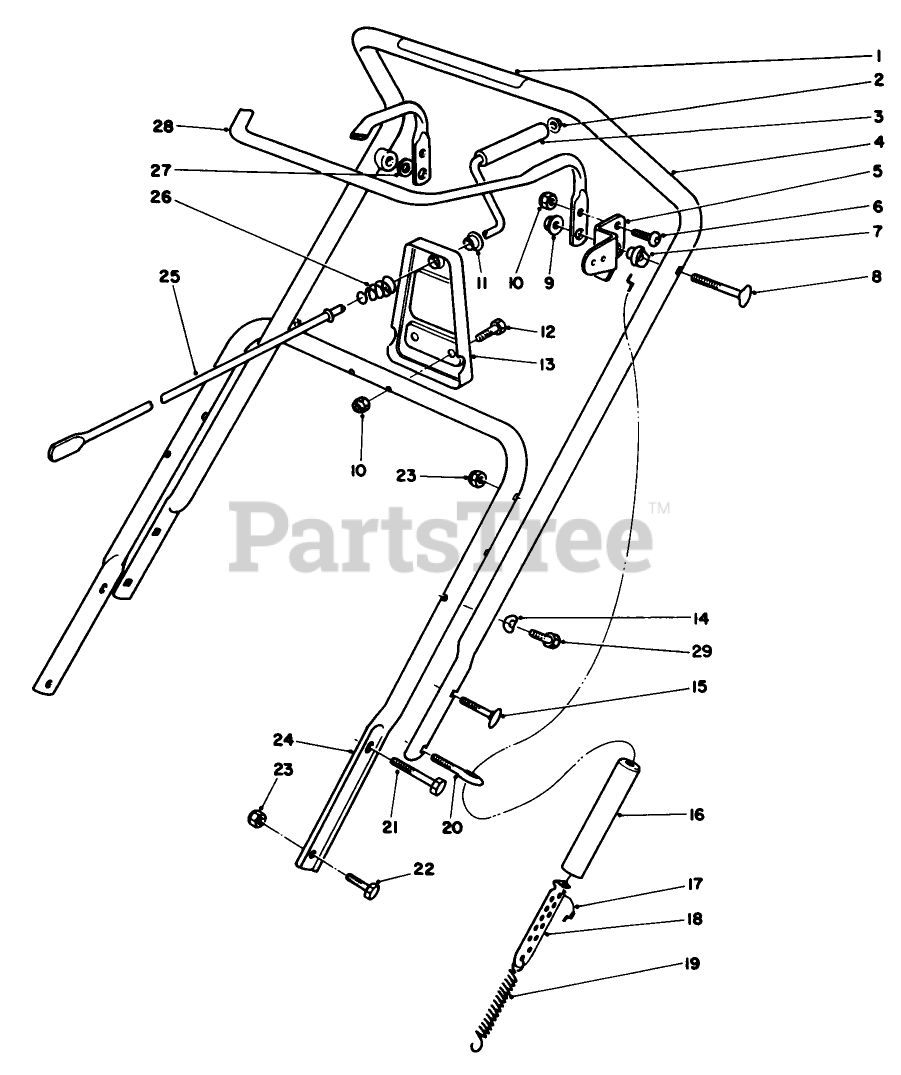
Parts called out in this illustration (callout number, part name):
1	Decal-Rotor Drive
2	216 Washer
3	GRIP-CONTROL, CHUTE
4	Upper Handle Assembly (Incl. Ref. #1)
5	Arm-Clutch Cable
6	SCREW-HSBH
7	SPACER-BAR, CONTROL
8	SCREW-HANDLE
9	NUT-LOCK, NI
10	NUT-LOCK, NI
11	Bushing
12	SCREW-HH
13	Support-Crank
14	WASHER
15	SCREW
16	COVER-SPRING
17	CLUTCH CABLE
18	ADJUSTER-CABLE
19	SPRING-EXTENSION
20	BOLT-EYE
21	SCREW-HH
22	SCREW-HH
23	NUT-LOCK, NI
24	LOWER HANDLE
25	ROD-CRANK, CHUTE
26	SPRING-COMPRESSION
27	WASHER
28	Bar-Control
29	SCREW
